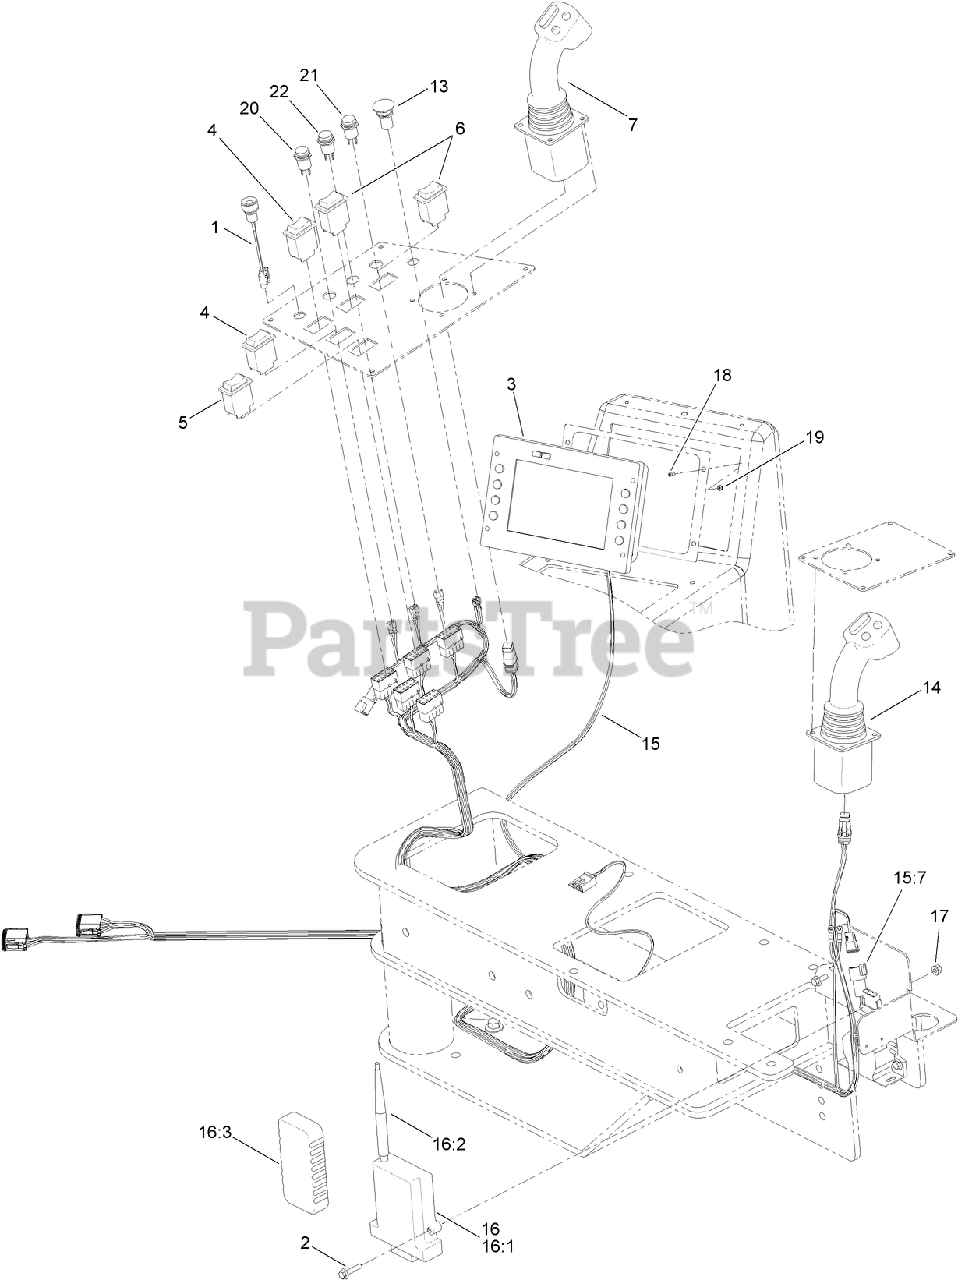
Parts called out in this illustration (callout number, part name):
1	SWITCH-START, GREEN BUTTON
2	SCREW-HHF
3	DISPLAY-DP600, UNPROGRAMMED
4	SWITCH-ROCKER, 2 POLE (ON/OFF)
5	SWITCH-ROCKER, 2 POLE
6	SWITCH-ROCKER, 1 POLE (ON)OFF/ON(OFF)
7	JOYSTICK-MODIFIED (LEFT HAND)
13	BUTTON-PUSH, RED MUSHROOM
14	JOYSTICK-CARRIAGE
15	HARNESS-WIRE, OPERATOR
15:7	RESISTOR-120 OHM
16	STANDARD EXIT SIDE LOCKOUT
16:1	BASE UNIT-LOCKOUT
16:2	ANTENNA-LOCKOUT
16:3	HANDHELD-LOCKOUT
17	NUT-FLANGE, NI
18	SCREW-PH
19	NUT-LOCK, NI
20	LAMP-INDICATOR, LED
21	LAMP-INDICATOR, LED
22	LAMP-INDICATOR, LED
